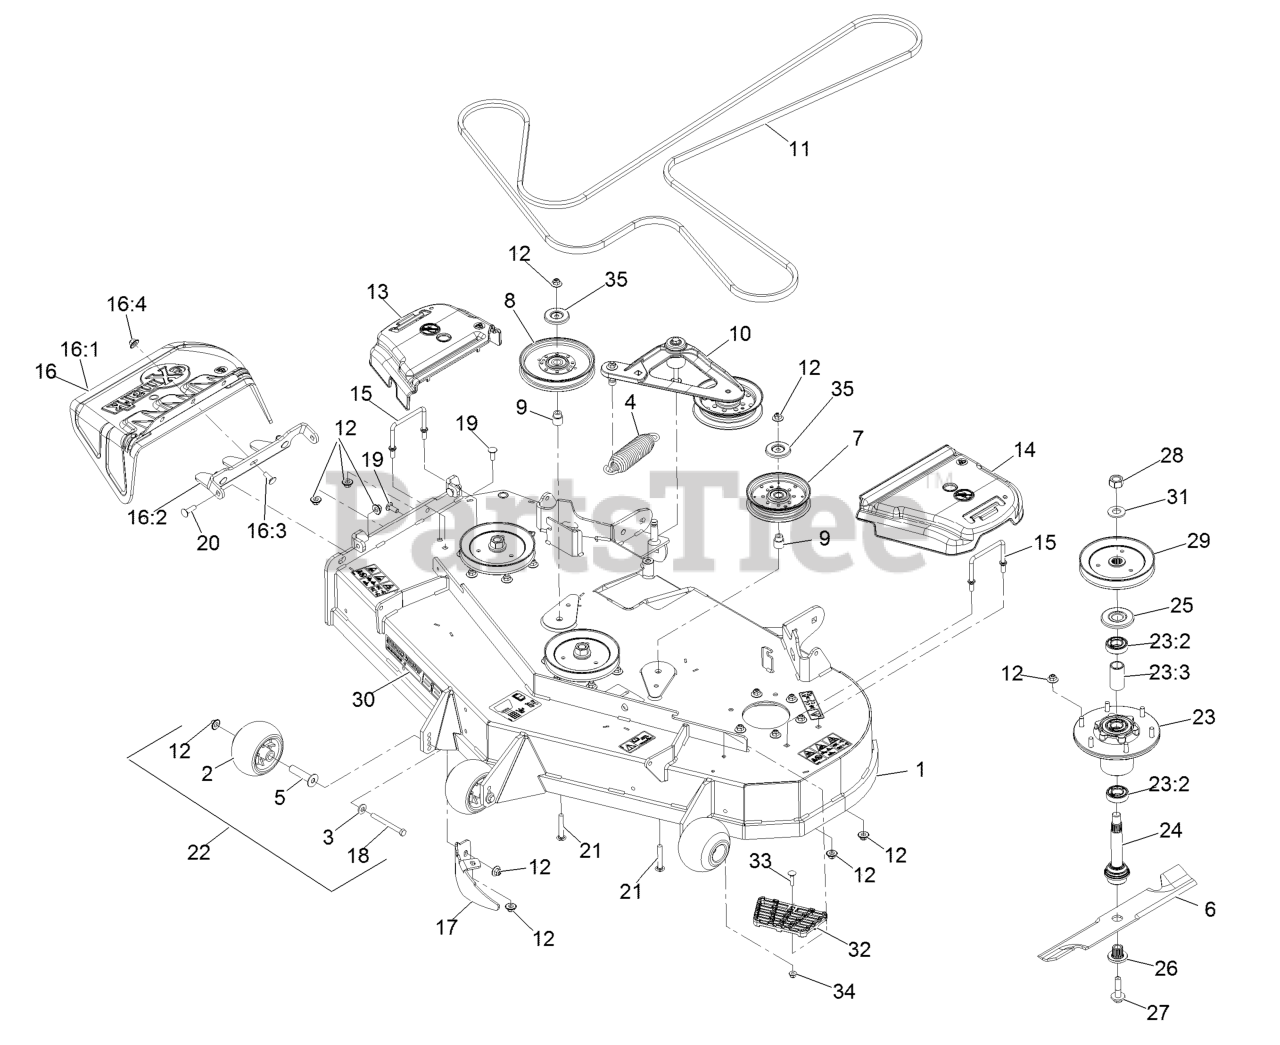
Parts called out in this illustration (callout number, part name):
1	ASM,DECK W/ DECALS 52
2	ROLLER-SCALP, ANTI
3	WASHER-BELLEVILLE
4	SPRING-EXTENSION
5	AXLE, ROLLER
7	PULLEY-IDLER, FLAT
8	IDLER-PULLEY
9	BUSHING-IDLER
10	DECK IDLER ASM
11	BELT,V-B X 186.00"
12	Nut-Nyloc 3/8-16 Flg
13	COVER-BELT, RH
14	COVER-BELT, LH
15	WIREFORM-COVER
16	ASM,DISCHARGE CHUTE
16:1	CHUTE,DISCHARGE
16:2	BRACKET,DISCHARGE CHUTE
16:3	SCREW-CARR
16:4	Nut-Nyloc 3/8-16 Flg
17	BAFFLE-DOGLEG, LZ-VT52
18	SCREW-HH 3/8-16 X 3 3/4 GR 8
19	SCREW-CARR
20	Bolt-Carriage 3/8-16 X 1 1/4
21	SCREW-CARR
22	KIT, ANTI-SCALP ROLLER
23	ASM-CUTTER HSG WITH BEARINGS
23:2	BEARING-BALL
23:3	SPACER-BEARING
24	ASM-SPINDLE AND SEAL
25	GUARD,BEARING TOP .989
26	BUSHING,SPLINED
27	SCREW,SEMS 1/2-20 X 2.19
28	NUT-HEX
29	SHEAVE,BLADE DRIVE 6.50
30	DECAL, 524
32	STEP-DECK
33	Bolt-Carriage 5/16-18 X 1 1/4
34	NUT-HF, NI
35	SHIELD-DUST
